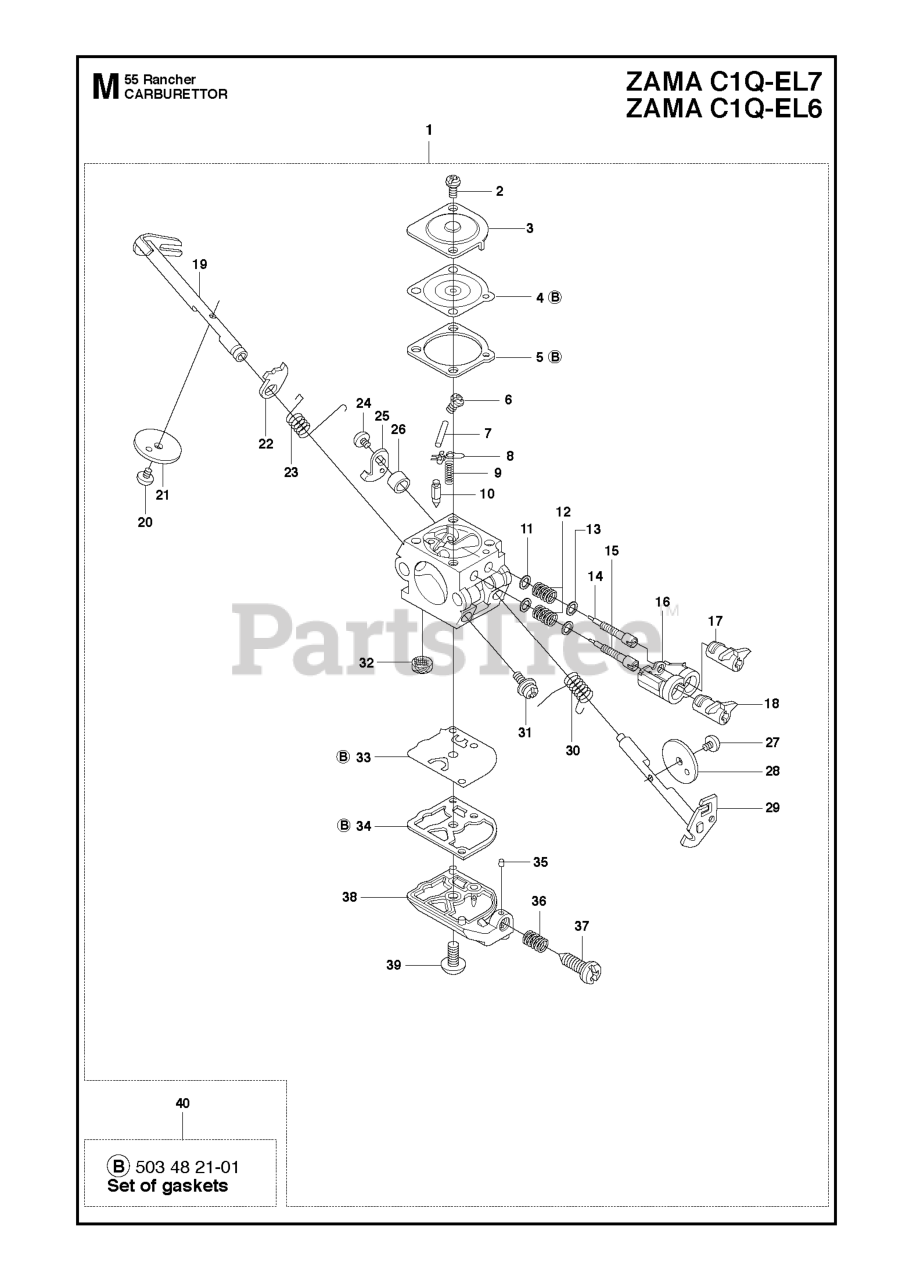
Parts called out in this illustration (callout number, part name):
1	CARBURETOR CIQ-EL6 ZAMA
1	CARBURETOR CIQ-EL7 EPA ZAMA
4	METERING DIAPHRAGM
5	GASKET METERING SIDE
7	PIN RETAINING SCREW
10	INLET NEEDLE
11	WASHER
12	SPRING
13	WASHER
14	HI-SPEED NEEDLE
14	LOW SPEED NEEDLE
15	NEEDLE
15	NEEDLE HIGH SPEED
17	LIMITER CAP
18	LIMITER CAP
19	CHOKE SHAFT
21	CHOKE FLAP
22	STARTER LEVER
25	STARTER LEVER
28	THROTTLEFLAP
29	THROTTLE SHAFT
30	SPRING THROTTLE
32	FUEL INLET SCREEN
33	PUMP DIAPHRAGM
34	GASKET PUMPSIDE
40	DIAPHRAGM GASKET KIT
